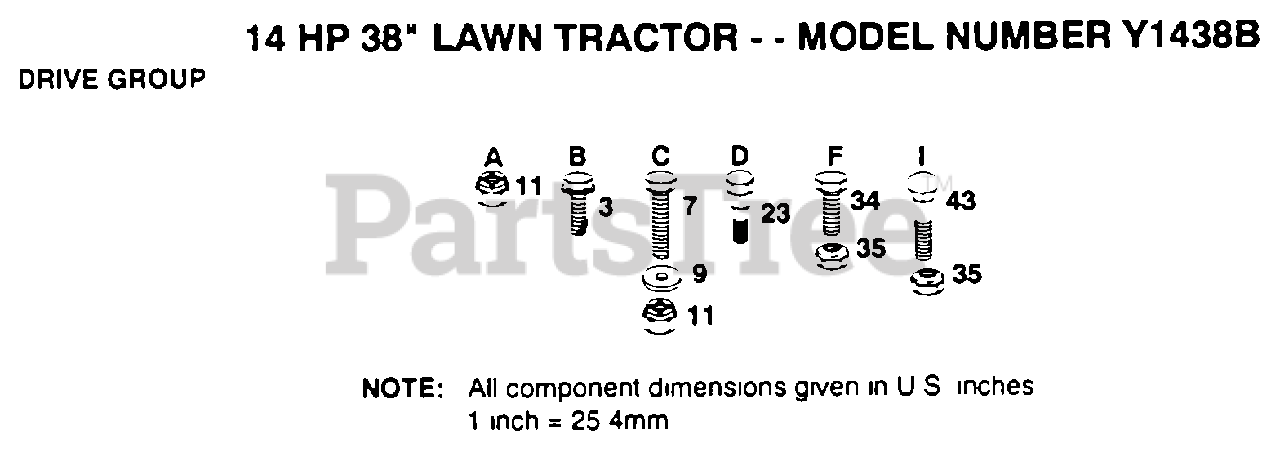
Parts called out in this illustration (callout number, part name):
3	SCREW
7	BOLT
9	WASHER
23	"BOLT, SHOULDER LT"
34	BOLT
43	BOLT
